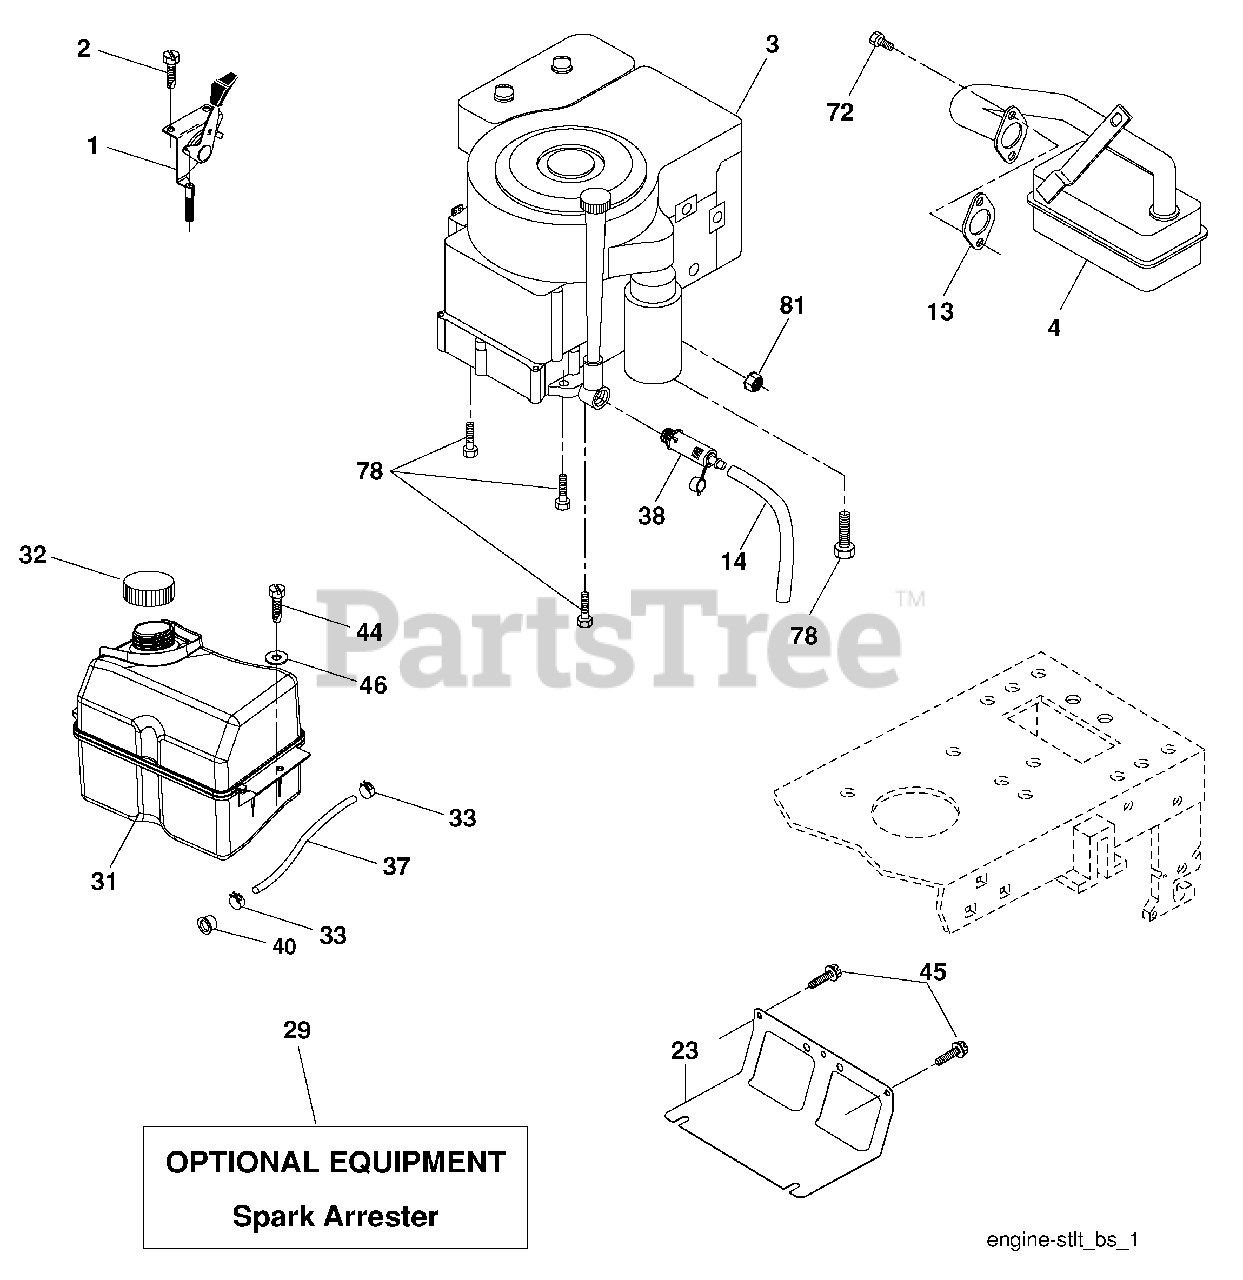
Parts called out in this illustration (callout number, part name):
1	Control Th/ch Flag
2	Screw Hex Thd Cut 1/4-20 x 1/2
4	Muffler Exhaust B&S
13	Gasket Eng 1 313 Id Tin Plated
14	Tube Drain Oil Easy
23	Shield BRN/DBR Guard
29	Kit Spark Arrester (Flat Scrn)
31	Tank Fuel Front
32	Cap Asm Fuel
33	Clamp Hose
37	Line Fuel 20"
38	Plug Drain Oil
40	Bushing Snap Nyl Blk Fuel Line
44	Screw Thdrol 1/4-20 x 3/4
45	Screw Hex Wsh Thdrol 3/8-16
46	Washer 9/32 x 7/8 x 16 Ga.
72	Screw Socket Head 5/16-18 x 3/4
78	Screw 3/8-16 x 1-1/4
81	Nut Keps Hex 1/4-20 unc
